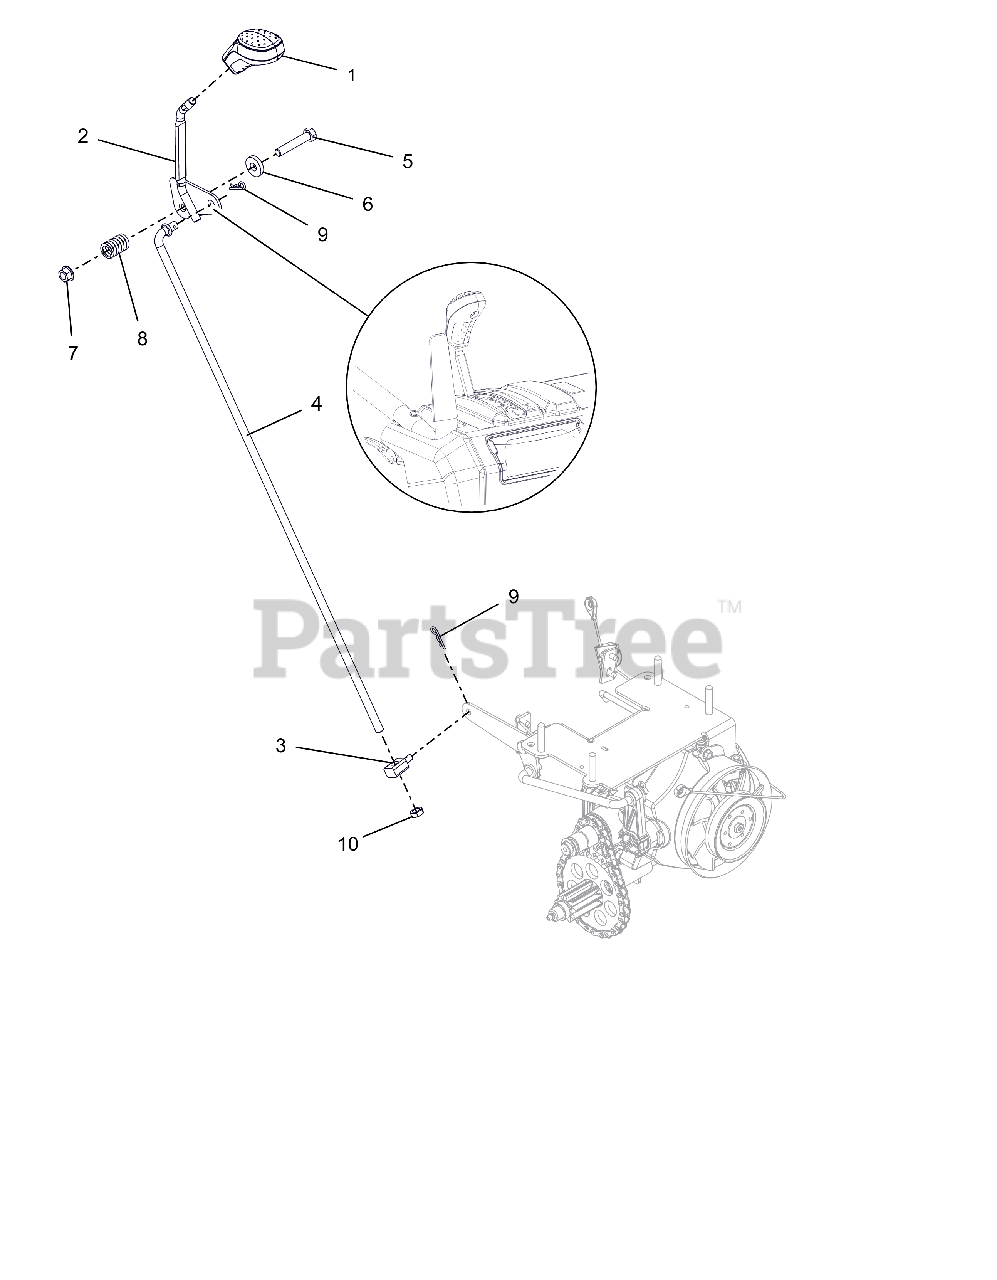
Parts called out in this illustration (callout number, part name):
1	KNOB, CONTROL, DASH
2	WELDMENT,LG DASH SPEED CONTROL
3	PIVOT,SHIFT ROD .375-16(TRUNN)
4	ROD, SHIFT-PRO
5	BLT,HEX .38-16X2.00 G5 ZCC
6	WSHR, FLT .406X1.00X.188 ZCC
7	NUT-LK-TOP-FLG .38-16 ZC120
8	SG-COMP .125X.781X1.250
9	PIN, HAIR #213 .08X1.19 ZCC
10	NUT-JAM .375-16 G2 ZCC
